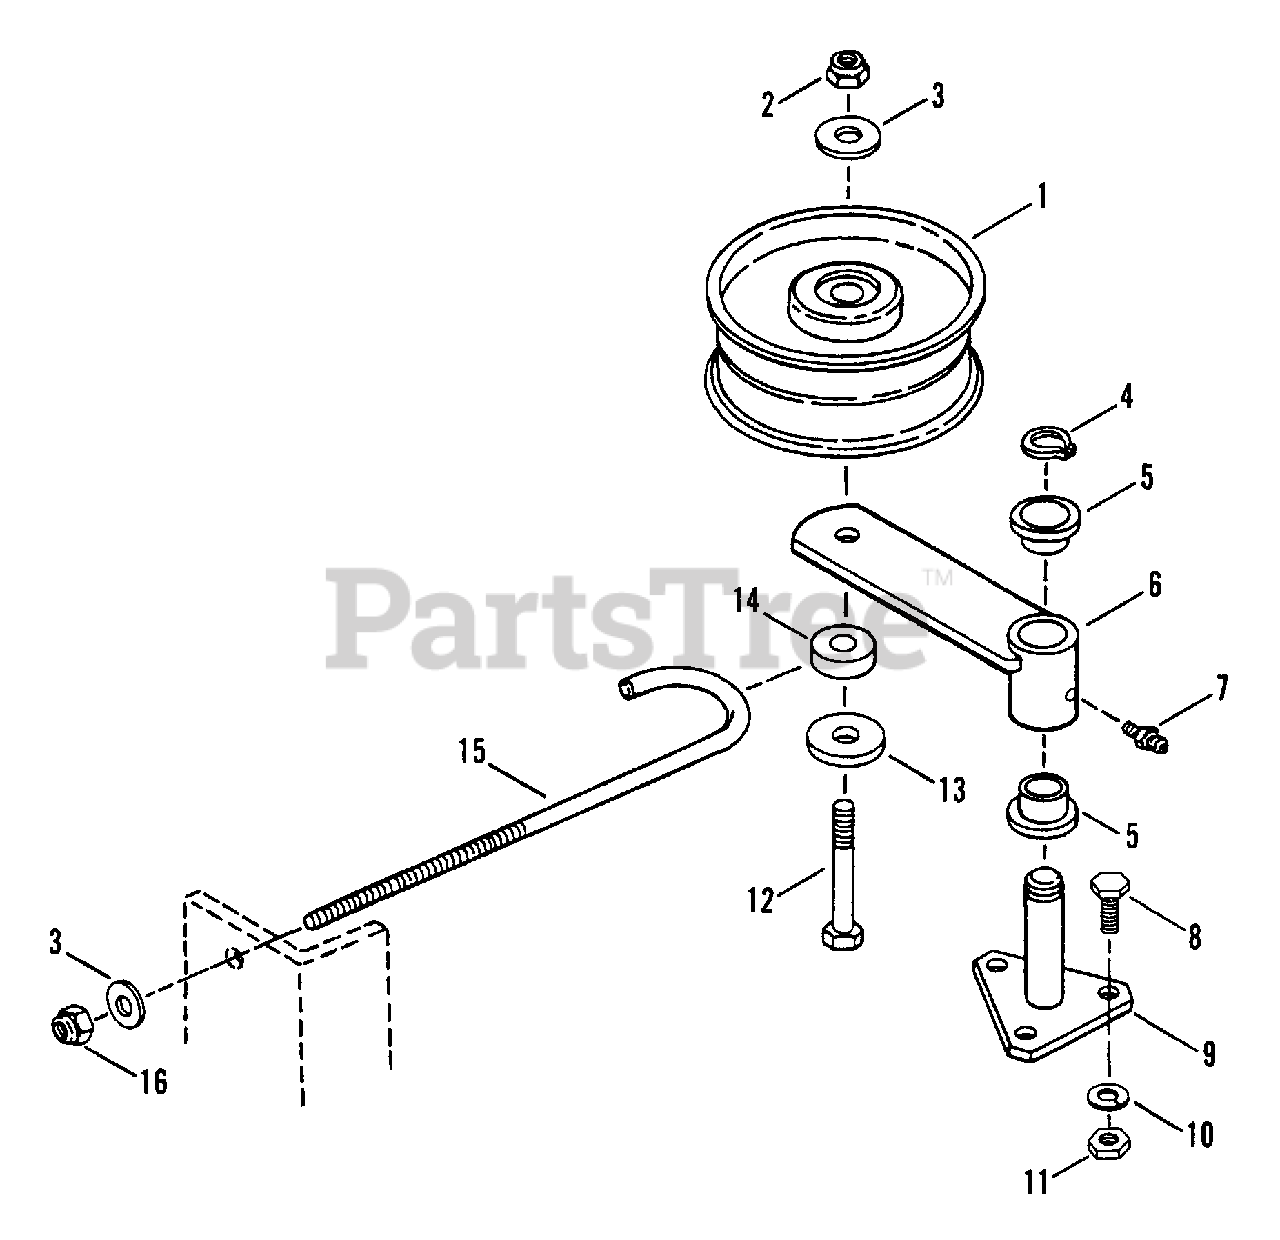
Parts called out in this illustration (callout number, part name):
1	PULLEY, Idler (5.00 OD)
2	NUT, 3/8-16 HEX NYLON LOCK
3	WASHER, 3/8" USS
4	RING, 1" Retaining
5	BUSHING
6	IDLER ARM (Weldment)
7	FITTING, Lube
8	BOLT, 3/8-16 X 1" GD5 CZ
9	PIVOT, Idler Arm
10	WASHER, 3/8" SPLIT LOCK
11	NUT, 3/8-16 Hex, Grade 5
12	BOLT, 3/8-16 X 2-3/4" GD5 CZ
13	WASHER, 13/32" Flat
14	BUSHING, 38" ID x 1" O.D. x 410"
15	HOOK, "J"
